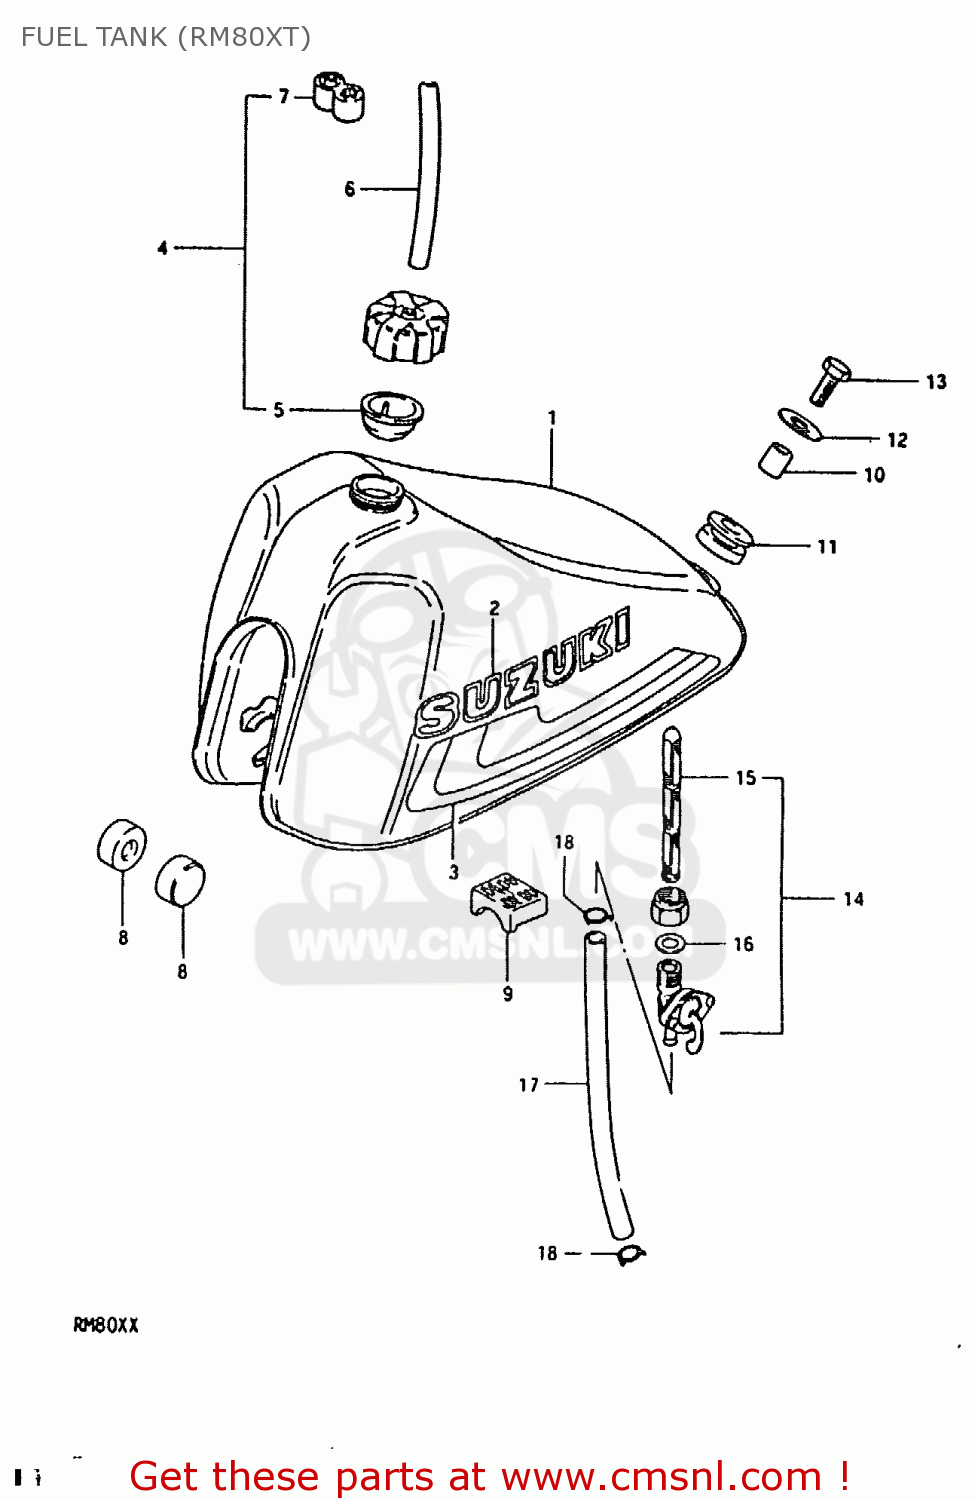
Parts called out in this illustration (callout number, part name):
1	TANK ASSEMBLY,FUEL
2	EMBLEM
3	TAPE SET,FUEL TANK
4	CAP ASSEMBLY,FUEL TANK
5	GASKET,FUEL TANK CAP
6	HOSE
7	CLAMP,FUEL TANK BREATHER HOSE
8	CUSHION
9	CUSHION,FUEL TANK
10	SPACER (8.2X12X17)
11	CUSHION
12	WASHER (8.5X29X1.6)
13	BOLT (8X30)
14	COCK ASSY,FUEL
15	FILTER,FUEL
16	GASKET,FUEL COCK (NAS)
17	HOSE
18	CLIP
